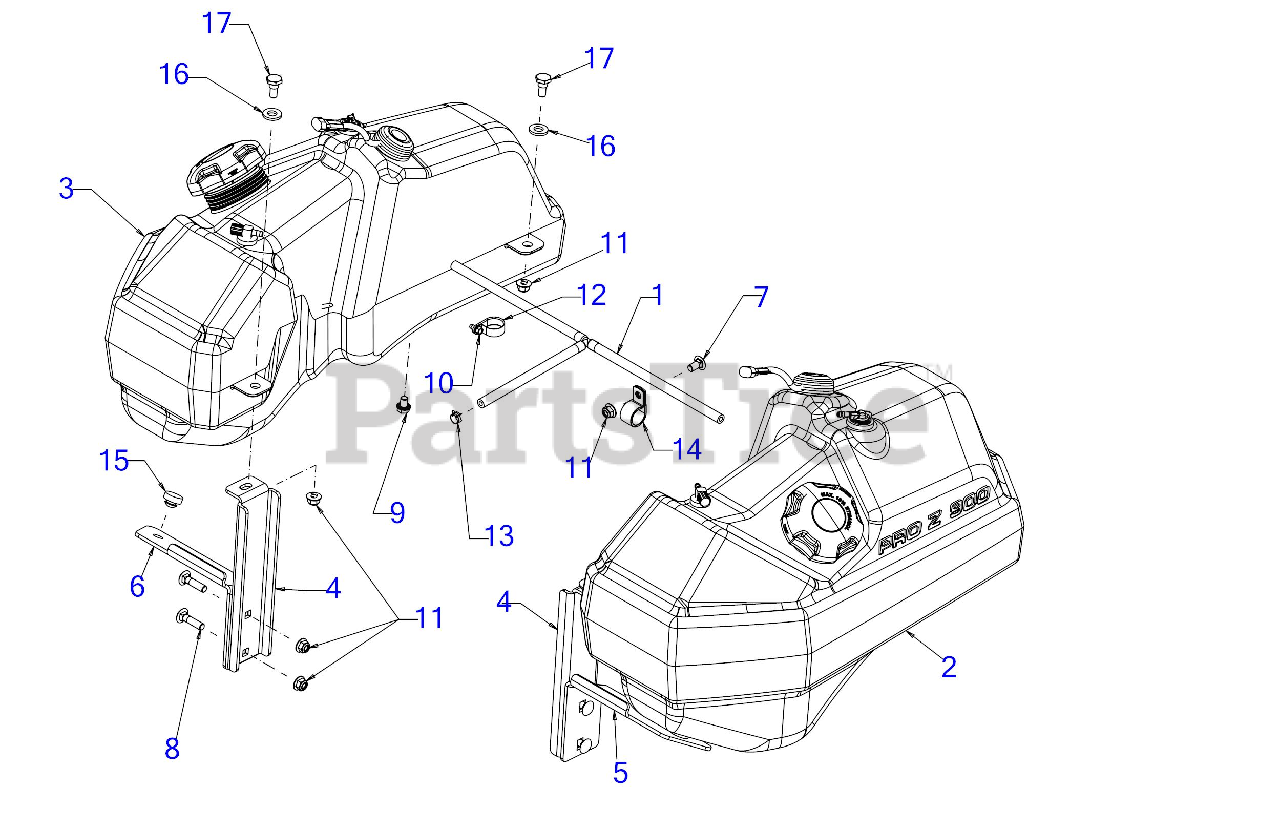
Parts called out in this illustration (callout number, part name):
1	FUEL LINE ASSEMBLY
2	FUEL TANK ASSEMBLY (RH) (7.25 GAL)
3	FUEL TANK ASSEMBLY (LH) (7.25 GAL)
7	CARRIAGE BOLT 3/8-16 x .750 GR5
8	CARRIAGE BOLT 3/8-16 x 1.50
9	SCREW 3/8-16 x .500 GR5
10	SCREW 1/4-20 X.500
12	DRAIN HOSE CLAMP
14	HOSE CLAMP 1.0"
15	RUBBER BUMPER 1.000 x .313
16	FLAT WASHER .510 x 1.000 x .125
17	SHOULDER SCREW .498 DIA x .340
